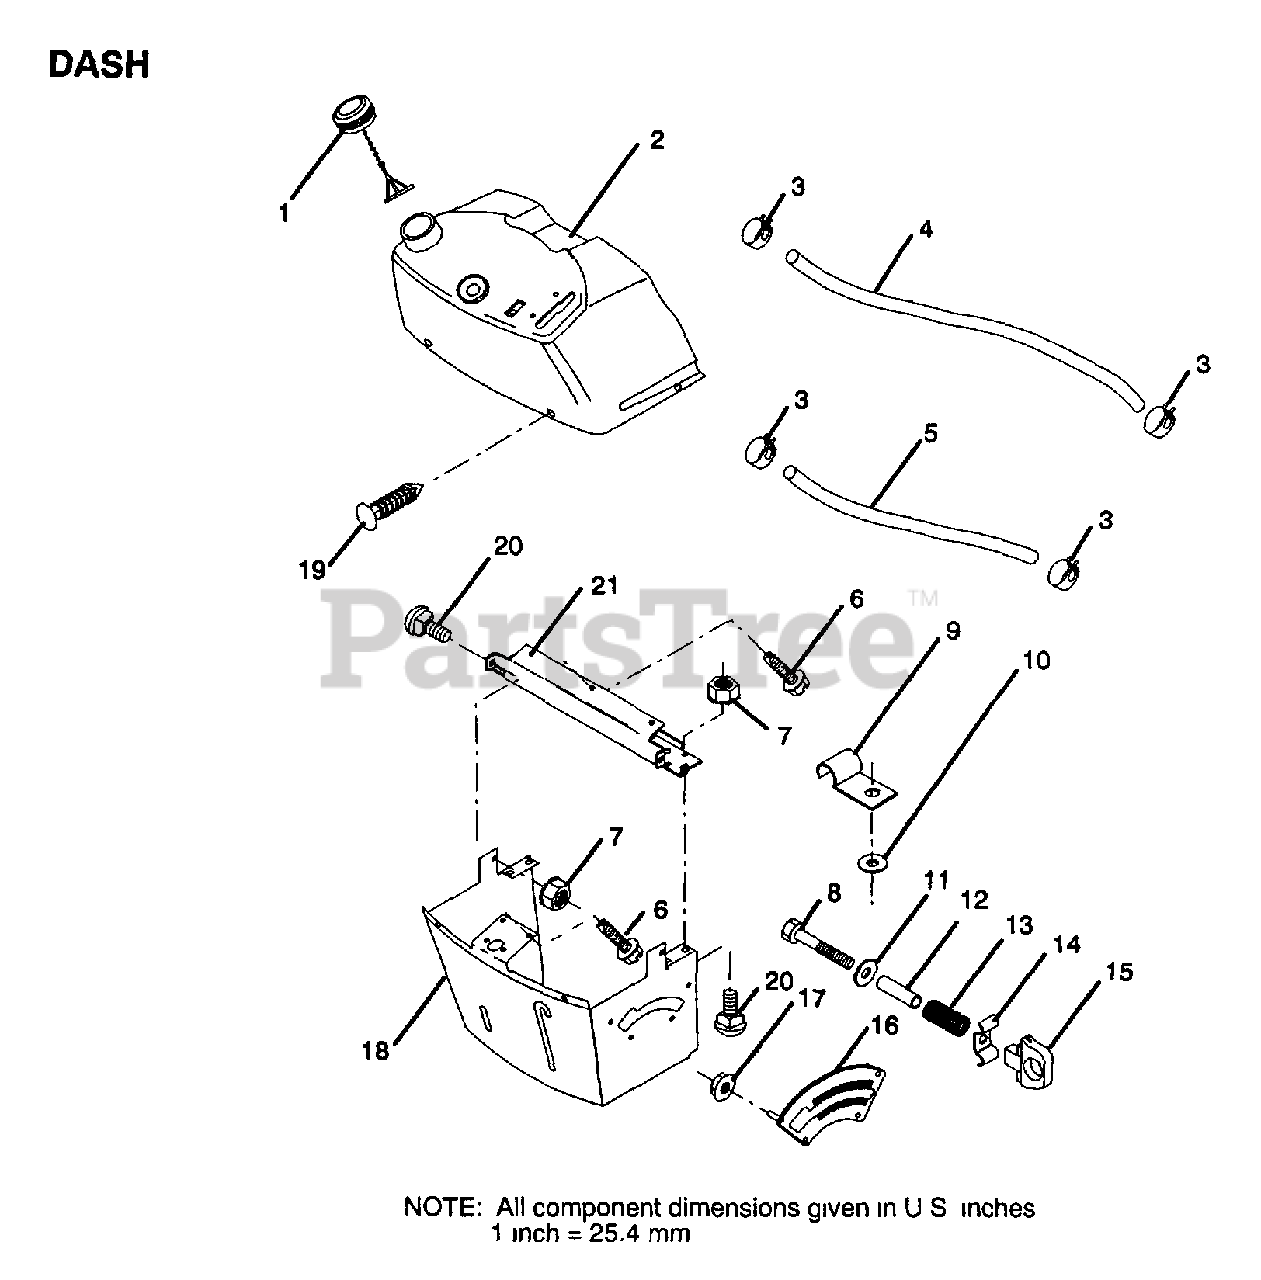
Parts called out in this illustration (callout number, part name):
3	HOSE CLAMP
4	FUEL LINE T
7	NUT
8	BOLT
9	CLIP T
10	WASHER PM
11	WASHER
12	SPACER SPLIT
13	SPRING T
14	HEIGHT ADJ
15	KNOB
16	ADJUSTER QUAD
17	NUT
18	SUPPORT DASH
19	SNAP
20	BOLT
21	"BRAKE,CROSS"
